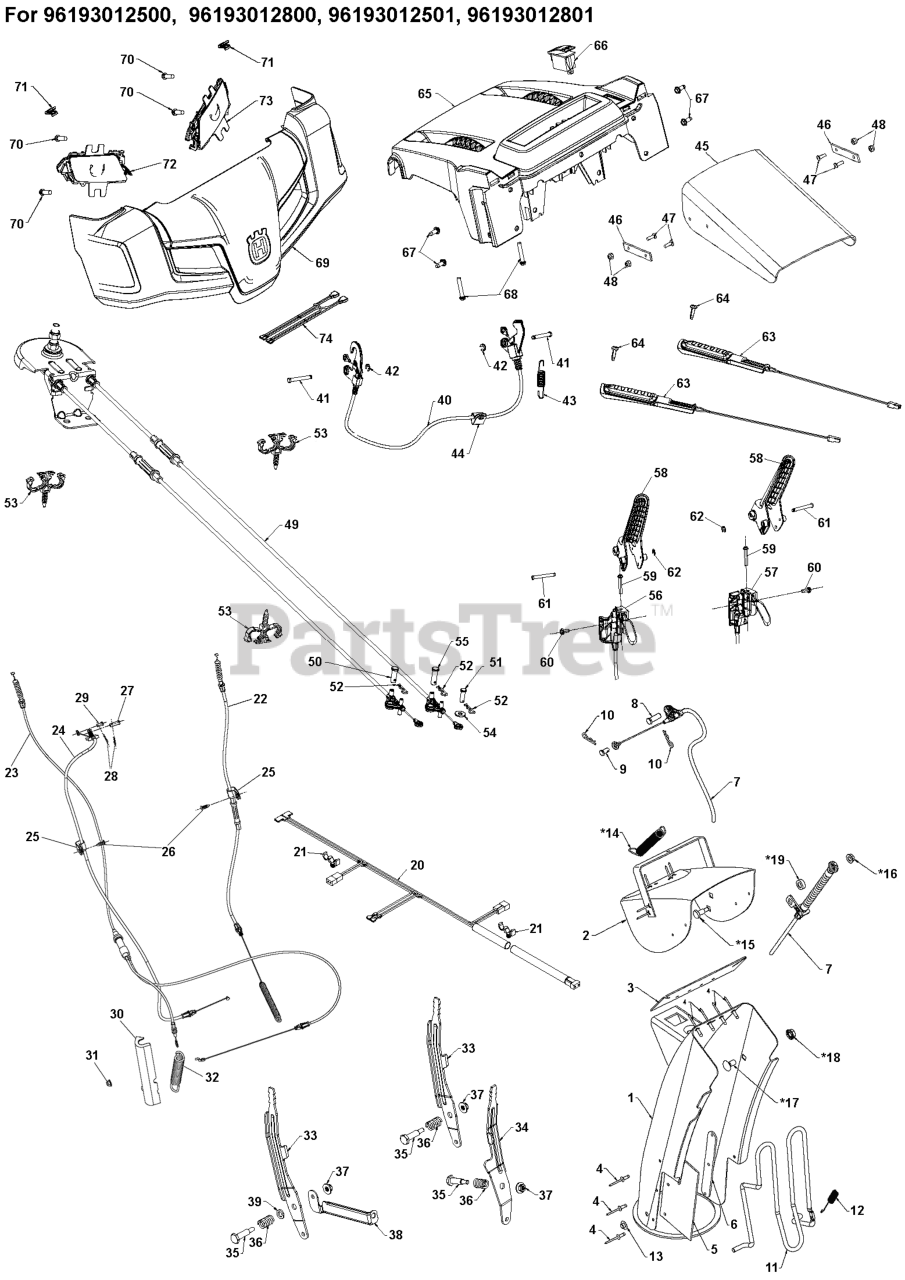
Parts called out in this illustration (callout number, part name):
1	ASM.CHUTE/DEFLECTOR.668
3	SEAL.DEFLECTOR
4	RIVET BLIND
5	SHIELD.SNOW.CHUTE
6	RP STRAP.SHEILD.RETAINER
7	CABLE.CONTROL.CHUTE.DEFLEC
7	CABLE CONTROL.CHUTE.DEFLECTOR.
8	PIN CLEVIS 5/16X.875
9	PIN CLEVIS .25 X .31
10	HAIRPIN.SOFT.ZINC.059X1.125
11	ROD.GUARD.CHUTE (2 2)
11	GUARD ROD CHUTE GUARD SHORT CL
12	SPRING.CHUTE.GUARD
13	NUT
20	HARNESS WIRE.LIGHT AND GRIPS
22	CABLE DRIVE WITH ADJUSTER
22	Cables
23	CABLE IMPELLER
24	Cables
24	CABLE.CONTROL.SPEED.DSST.OPP
25	CLIP.CABLE.BLK
26	FASTENER.PUSH.O.250X0.783
27	PIN CLEVIS 5/16X.875
28	HAIRPIN.SOFT.ZINC.059X1.125
29	PIN CLEVIS .25 X .31
30	COVER AUGER CABLE
31	NUT HEXAGON FLANGE 5/16-18 ST
31	NUTNYLOK.FLRANGE.5/16-18
32	SPRING EXTENSION; AUGER EXTENS
33	LEVER.CONTROL.SPEED/DEFLEC.BLK
34	LEVER.CONTROL.CHUTE.ROTATON.BL
35	BOLT SHOULDER_HEX HD_1/4-20_3/
36	SPRING.COMPRESSION.82LBS
36	BOLT SHOULDER_HEX HD_1/4-20_3/
37	NUT HEX_LRG FLG_1_4-20_LOCK
38	BRACE.SUPPORT.SPEED.BLACK
39	WASHER.FLAT.625 X .375 NYLON
40	CABLE INTERLOCK CONTROL ACETAL
41	PIN.GROOVED
43	SPRING RETURN_INTERLOCK_DSST
44	CLIP.CABLE.BLK
45	SHIELD.DEFLECTOR.BLACK.SNOW
46	STRAP.DEFLECTOR.SHEILD
47	SCREW.MACHINE.8-32 X 1/2-BLK
48	NUT.HEX.NYLOCK
49	CABLE ASSY CONTROL
50	PIN CLEVIS 5/16X.875
51	PIN.CLEVIS
52	HAIRPIN.SOFT.ZINC.059X1.125
53	CLIP.CONDUIT.DOUBLE LOOP
54	WASHER FLAT_.250 X .625 X .06
55	PIN CLEVIS CLEVIS
56	CABLE.POWER STEERING.LHS
57	CABLE.POWER STEERING.RHS
58	LEVER ENGAGMENT
59	SCREW HEX_WASH_13-16 X 1.50_H
60	SCREW 14-20 X 5/8
61	PIN.GROOVED
63	GRIP.HANDLE.HEATED
64	SCREW.PAN.HD.TORX.1/4-20X.750
65	CONSOLE BASE MULTI CONTROL
66	SWITCH HEATED GRIP BLK
67	SCREW 14-20 X 5/8
68	SCREW HEX_WASH_13-16 X 1.50_H
69	COVER CONSOLE_ASM_HUSQVARNA
70	SCREW.HWH.13-16-5.8.BZP
71	CLIP PANEL ERGO 30603
72	LIGHT ASM.HUSQVARNA.RH
73	LIGHT ASM.HUSQVARNA.LH
74	HARNESS.WIRE.LIGHT.JUMPER
